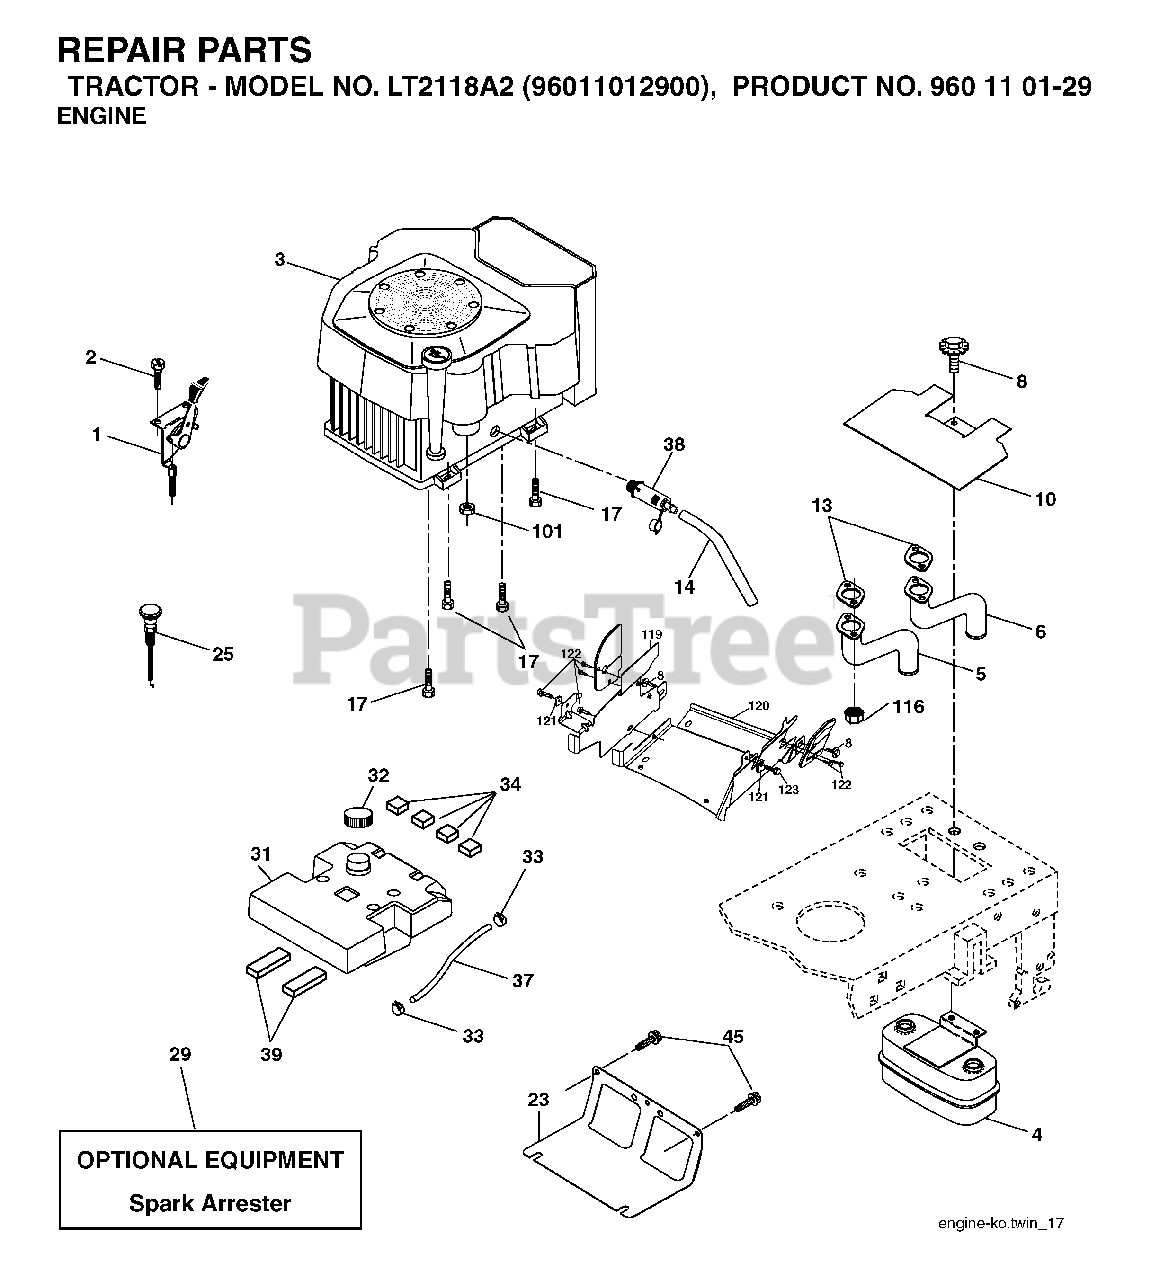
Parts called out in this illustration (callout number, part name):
1	CONTROL.THROTTLE.KAWA
2	SCREW
4	MUFFLER.TWIN.CYL.LOW.TONE
5	PIPE-EXHAUST LH
6	PIPE-EXHAUST RH
8	BOLT, 5/16-18 X 1 3/4
10	RP SHIELD HEAT MUFFLER
14	TUBE, DRAIN OIL ASM.
23	SHEILD.BROWNING.DBR.GUARD
25	CONTROL, CHOKE
29	ARRESTER SPARK (OPTIONAL)
31	TANK.FUEL(3.5.GAL)
32	FUEL CAP
33	HOSE CLAMP
34	PAD-SPACER LT
38	PLUG DRAIN OIL EASY
39	PAD IDLER TI
45	SCREW, 3/8-16X3/4
101	FLANGE NUT
116	NUT.HEX.FLANGE.TOPLOCK
122	SCREW.1/4-20X5/8
123	SCREW, 5/16-18 X 1/2
